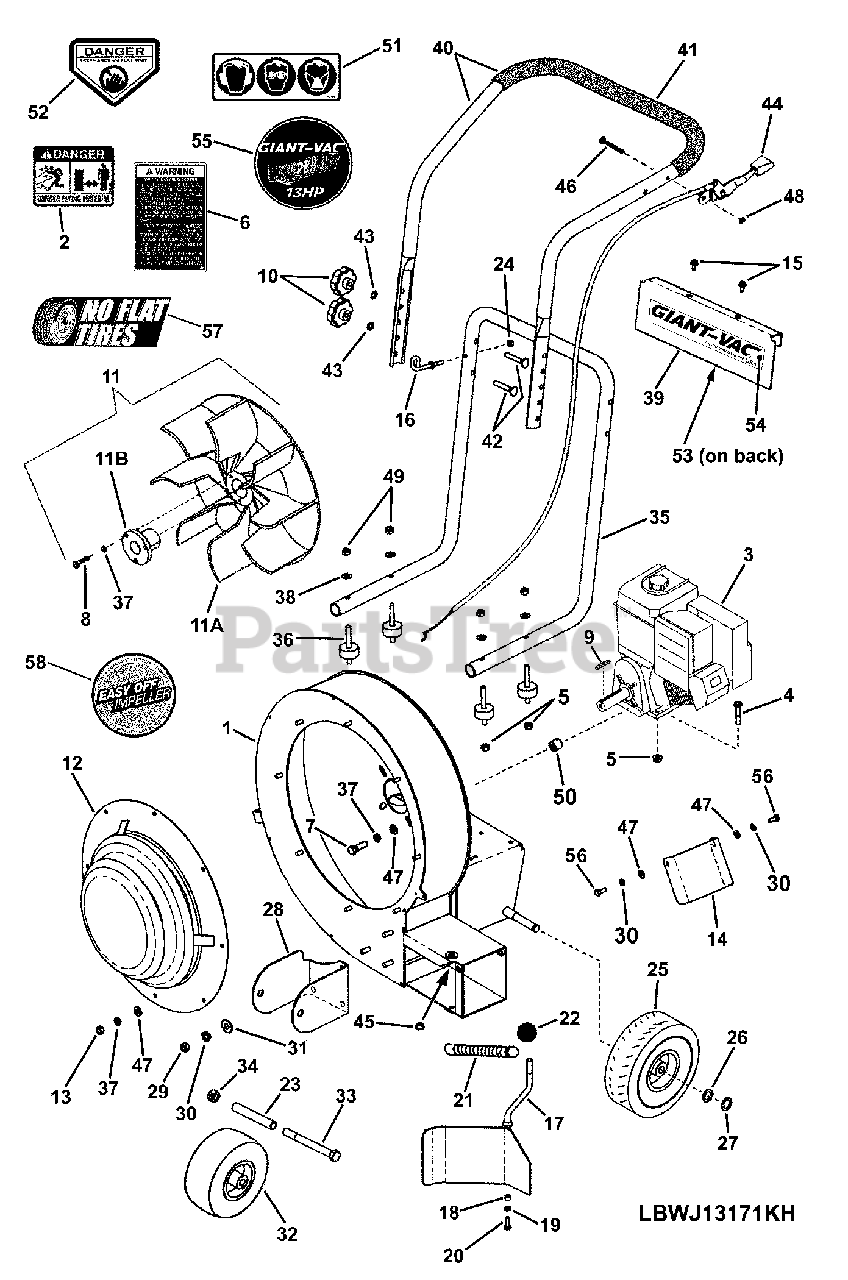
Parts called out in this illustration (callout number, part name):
1	WELDMENT, Housing- 85KWJ & 13KWJ
2	DECAL, Thrown Objects, Large
4	SCREW, 5/16-18 x 1-1/2 Hex Head Cap, GR 5
5	NUT, 5/16-18 Hex Flange Lock, GR 5
6	DECAL, Warning- Leaf Blower
7	SCREW, 5/16-24 x 1-3/4" Hex Head Cap, GR 5
8	SCREW, 5/16-18 x 1-1/4", Hex Head Cap, GR 5
9	KEY, 1/4" Square x 2"
10	KNOB, Fluted- Folding Handles (5/16-18 thread)
11	ASSEMBLY, 17" 8 Curved Blade Impeller
11A	IMPELLER, Cast, 17" O.D.
11B	HUB, Taper-Lok, Type 1 (2.938 OAL)
12	WELDMENT, Intake Baffle- WJ- 17"
13	NUT, 5/16-18 Hex, GR 5 or B
14	DEFLECTOR, Side Air- WJ- 17"
15	SCREW, 5/16-18 x 5/8" Hex Washer Self-Tap
16	GUIDE, Rope (1/4-20 thread)
17	** WELDMENT, Door WJ- 17"
18	BUSHING, Steel .250 ID x .375 OD x .25 Long
19	WASHER, 1/4" Split Lock
20	SCREW, 1/4-20 x 3/4" Hex Head Cap, GR 5
21	SPRING, Extension
22	KNOB, Ball Hand Lever- 3/8-16 Metal Insert
23	TUBE, Front Wheel- Extreme
24	NUT, 1/4-20 Hex Center Lock, GR 5 or B
25	ASSY., Wheel & Tire 410/350-4 "Flatfree"
26	WASHER, .64 x .99 x .05 Flat
27	RING, External Retaining (TRU1500-62)
28	***BRACKET, Front Wheel, High Rise
29	NUT, 3/8-16 Hex, GR 5 or B
30	WASHER, 3/8" Split Lock
31	WASHER, 3/8" Flat
32	ASSEMBLY, Tire & Wheel 9 x 350-4 "Flatfree"
33	BOLT, 1/2-13 x 5" Hex Head Cap
34	NUT, 1/2-13 Hex Center Lock, GR 5
35	HANDLE, Lower Folding- Wide- Blower
36	MOUNT, Vibration (5/16-18 thread- both ends)
37	WASHER, 5/16" Split Lock
38	WASHER, 5/16" Curved
39	DASH PANEL, Blower- Wide
40	ASSY, Upper Handle & Grip- Wide
41	GRIP, 1.0 x 21-1/2" Foam
42	BOLT, 5/16-18 x 2", Curved Head Square Neck, GR 2
43	WASHER, 5/16" Internal Tooth Lock
44	THROTTLE CONTROL, Kohler
45	BUSHING, Flanged .375 x .500 x .25 (.625 x .063 Flange)
46	SCREW, 1/4-20 x 2" Hex Head Cap, GR 5
47	WASHER, .34 x .69 x .08 Flat
48	NUT,1/4-20 Hex Nyloc
49	NUT, 5/16-18 Hex Nyloc
50	SPACER, .375 I.D. x .750 O.D. x .750
51	DECAL, Personal Protection
52	DECAL, Danger, Cut Finger
53	DECAL, GIANT-VAC (Small)
54	DECAL, GIANT VAC
55	DECAL, 13 HP Whisper Jet
56	SCREW, 3/8-16 x 1" Hex Head Cap, GR 5
57	DECAL, No Flat Tire
58	DECAL, Easy Off Impeller
